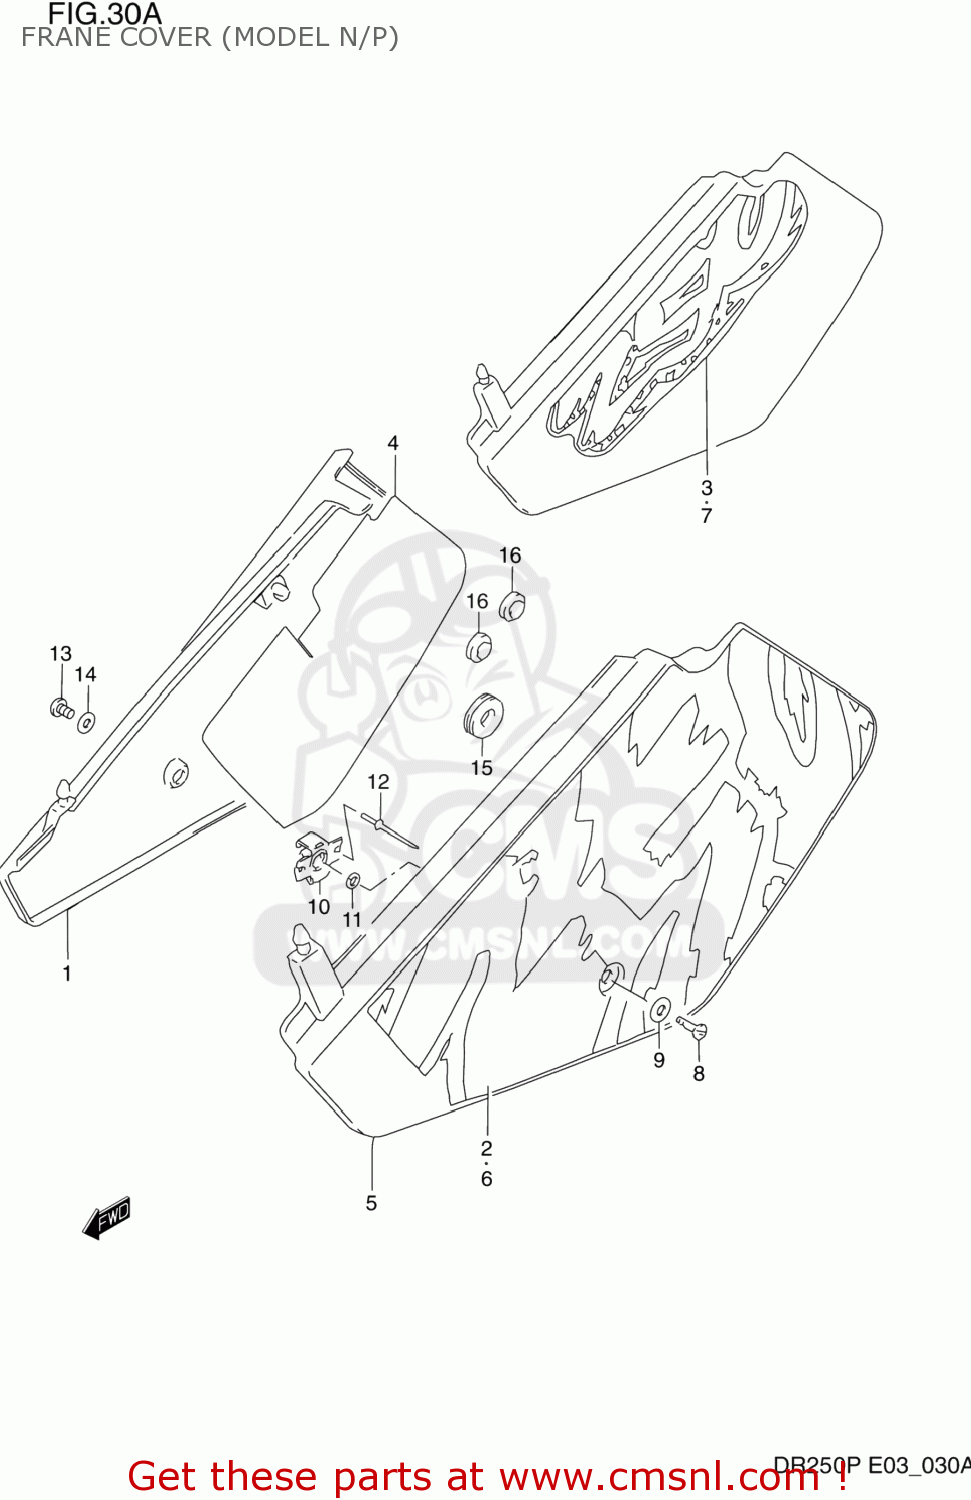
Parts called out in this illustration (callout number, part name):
1	COVER,FRAME,R(WHITE)
2	TAPE,FRAME COVER,RIGHT
3	EMBLEM,FRAME COVER,RIGHT
4	SHIELD,FRAME COVER,R
5	COVER,FRAME,L(WHITE)
6	TAPE,FRAME COVER,LEFT
7	EMBLEM,FRAME COVER,LEFT
8	STUD,FRAME COVER,LEFT
9	WASHER(7.2X18X1.6)
10	RETAINER,FRAME COVER STUD,L
11	PLATE,FITING
12	RIVET
13	SCREW
14	WASHER
15	CUSHION
16	CUSHION
